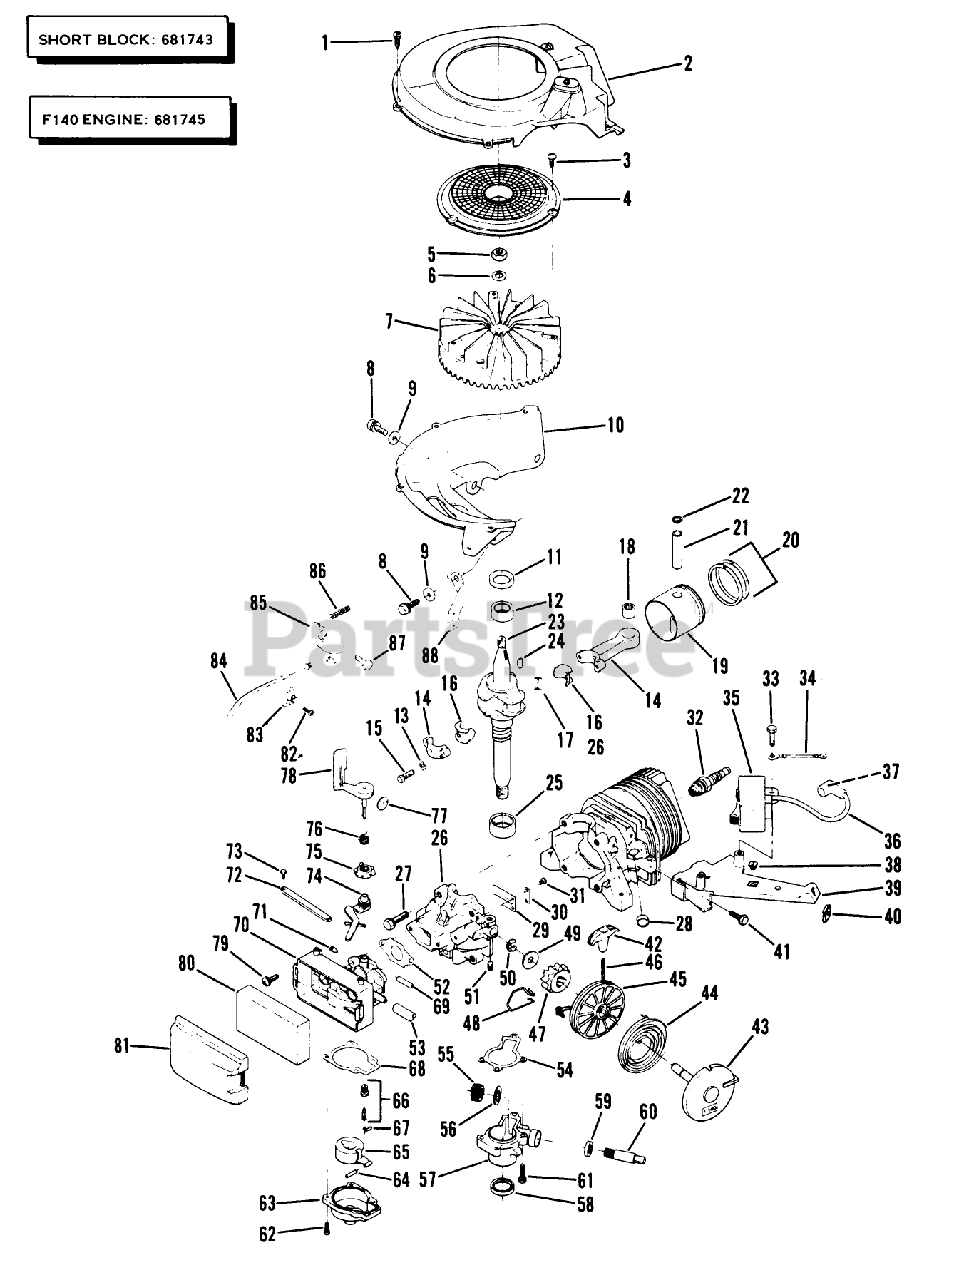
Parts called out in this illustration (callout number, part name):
2	AIR BAF&EYELET S
3	SCREW F
5	NUT
8	SCREW S
9	Washer
12	BEARING V
15	SCREW
16	LINER ASM
18	BEARING AY F
22	RING-RETAINING
24	KEY
25	BEARING S
27	SCREW S
28	PLUG-CORE VF
30	PLATE-BACKUP, REED
36	HT LEAD&COVER XEV
38	NUT-CLIP
40	NUT - SPEED S
42	HANDLE STARTER S
44	SPRING S
48	SPRING F
49	WASHER S
51	SET SCREW
52	GASKET CARB S
54	GASKET S
55	GEAR, DR SHAFT S
56	THRUST WASHER
59	SEAL S
62	SCREW-HH
69	TUBING PRIMER S
71	F-SCREW CARB
74	LEVER
75	ADJUSTMENT COLLAR
76	SPRING
77	DISC S
79	SCREW
83	CLIP S
85	LEVER LOCKOUT S
87	BOLT S
